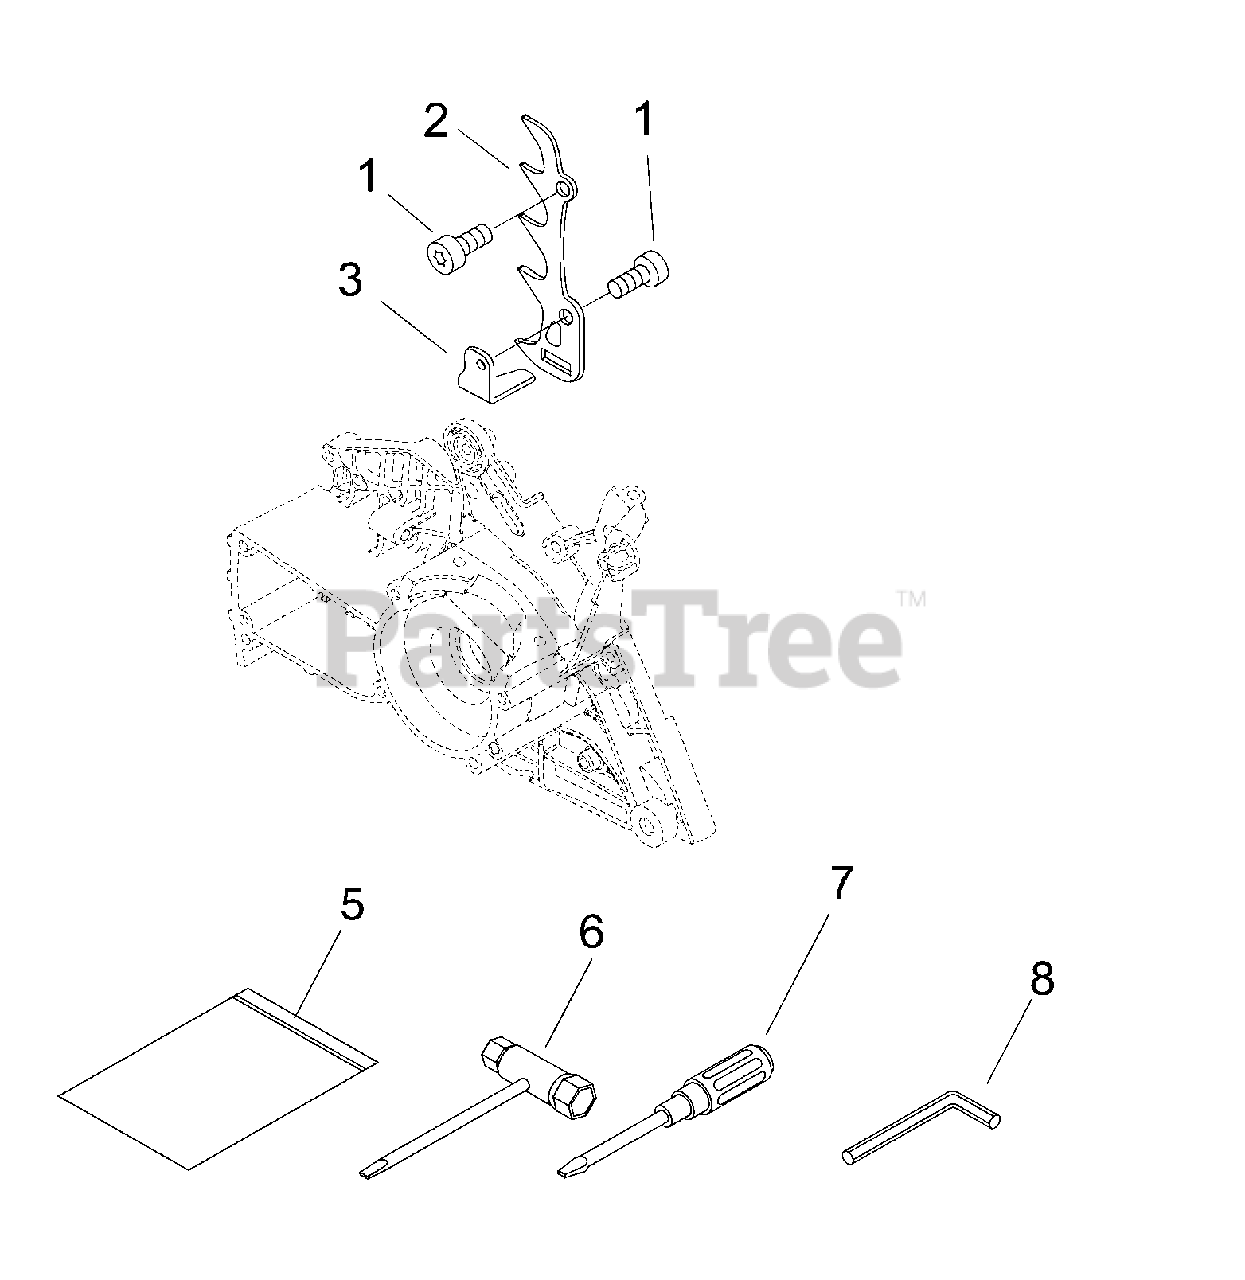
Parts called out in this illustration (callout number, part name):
1	BOLT, TORX 5×16
2	SPIKE, BUMPER
3	CHAIN CATCHER
5	BAG, TOOL
6	T-WRENCH 13×19 L= 180
7	SCREWDRIVER 50MM
8	WRENCH, ALLEN
